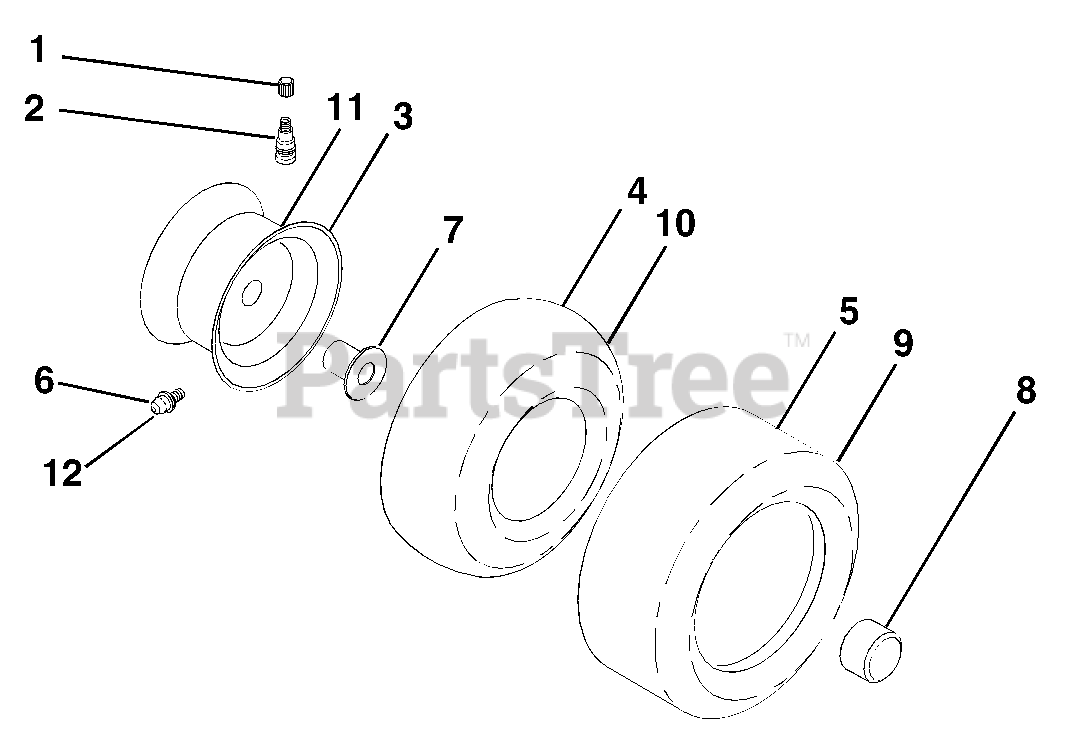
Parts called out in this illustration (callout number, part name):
1	Cap, Valve, Tire
2	Stem, Valve
3	Rim Assembly, Front
4	Tube, Front (Service Item Only)
5	Tire, Front
6	Fitting, Grease (Front Wheel Only)
7	Bearing, Flange (Front Wheel Only)
8	Cap, Axle (Front Wheel Only)
9	Tire, Rear
10	Tube, Rear (Service Item Only)
11	Rim Assembly, Rear
12	Fitting, Grease
